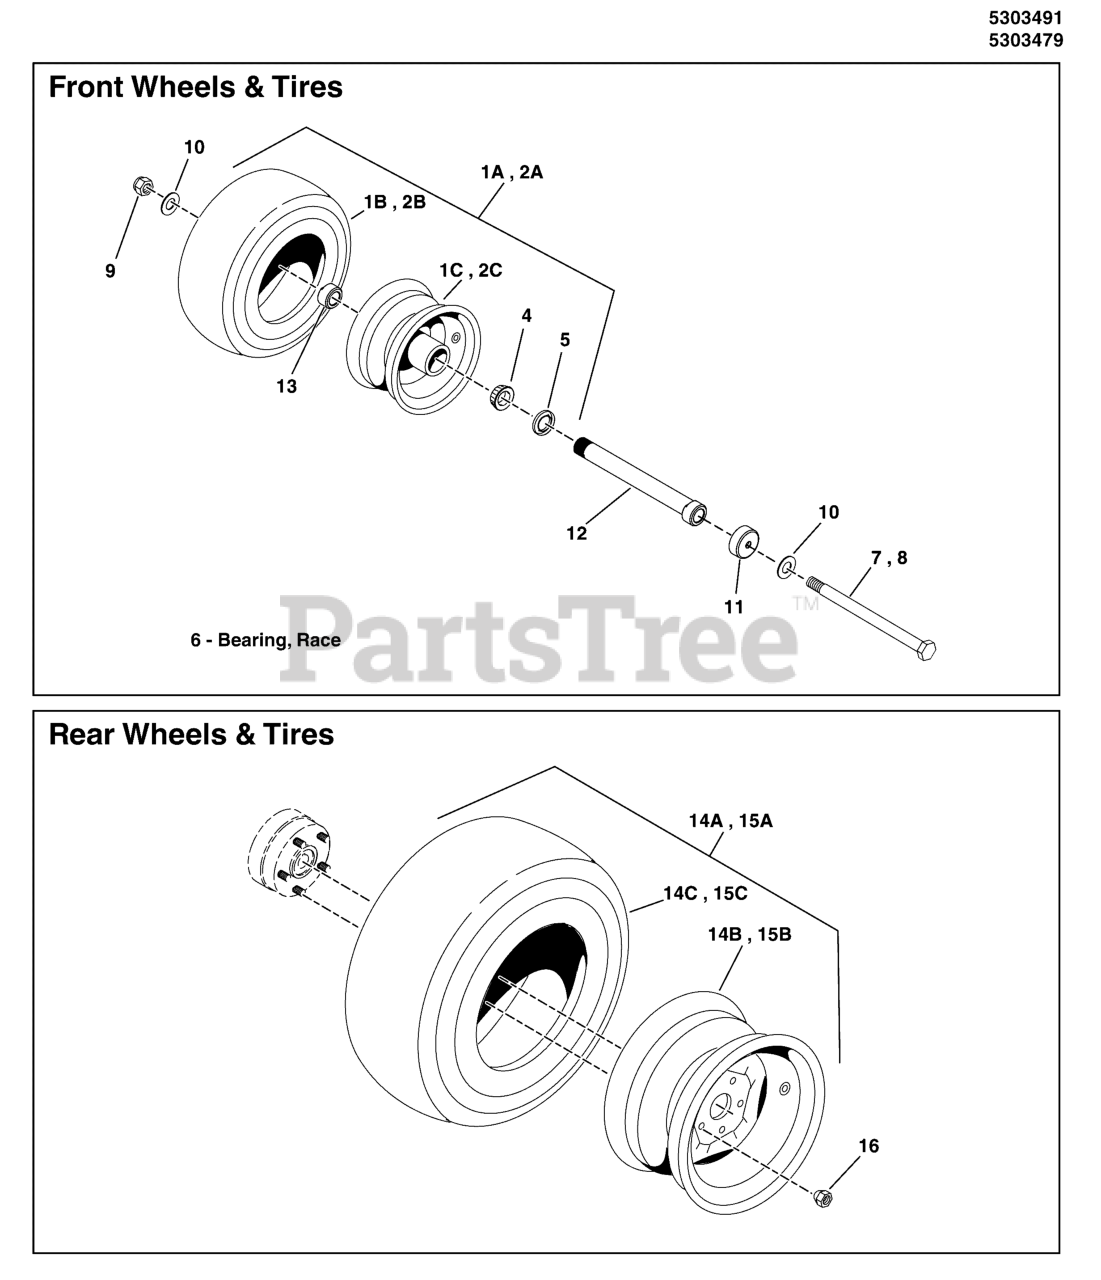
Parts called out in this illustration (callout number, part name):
1A	TIRE, CASTER, 13 X 5.00-6
1B	TIRE ONLY (SV)
2A	TIRE ASSM, 13 X 6.5 - 6, PNE / TB
2B	TIRE, RUBBER ONLY
3	WHEEL ASSY, 13 X 5 X 6, SILVER (SV)
4	BEARING, Tapered Roller
5	SEAL, GREASE
7	BOLT, 1/2-13 X 8 GD5 YZ
8	BOLT, 1/2-13 X 9 GD5 YZ
9	NUT, Hex Flange, Nylock, 1/2-13
10	WASHER, 1/2 SAE
11	DEBRIS, COVER, CASTER WHEELS
12	BEARING ADJUSTER, SPACER, 7.062 LG
13	NUT, BEARING ADJUSTER, AXLE
14A	TIRE ASSEMBLY
14B	WHEEL, 12 X 7, 5/4.5, 1.13 OFFSET (SV)
14C	TIRE, Rear, 23 x 9.5 x 12
15A	TIRE/WHEEL ASM, 23X10.5-12, TURF SMART
15B	WHEEL, 12 X 8.5, 5/4.5, 1.3 OFFSET (SV)
15C	TIRE, 23 X 10.5-12NHS, TURF SMART (SV)
16	NUT, 1/2-20, FOR WHEEL BOLT SILVER
